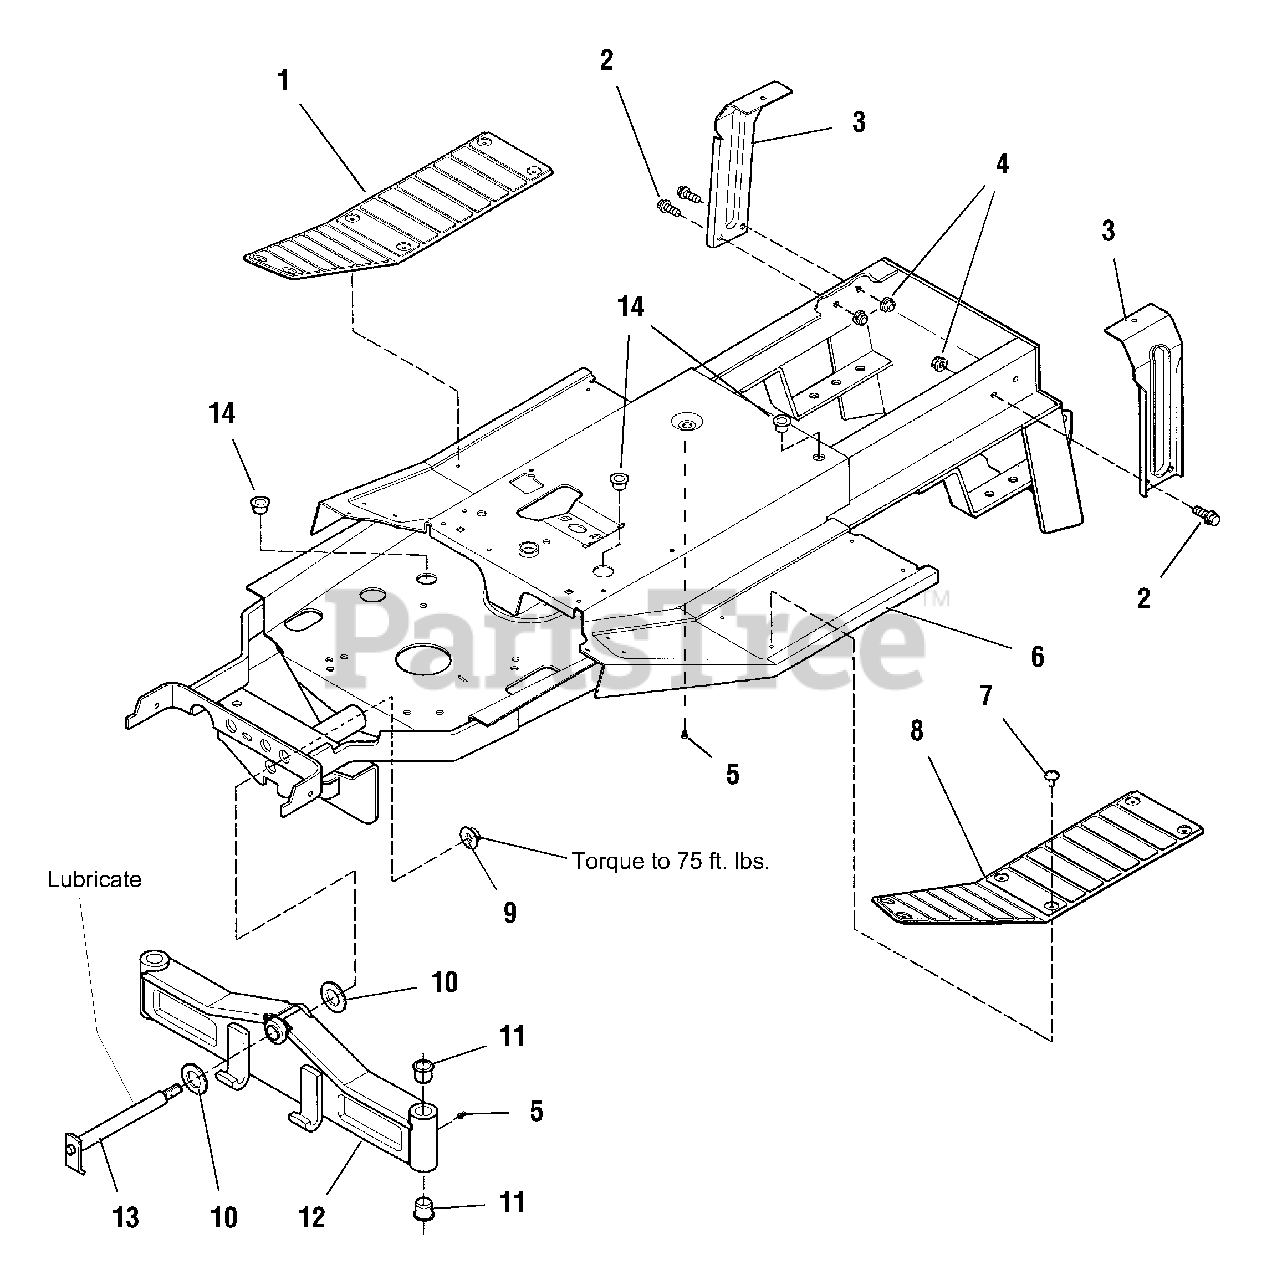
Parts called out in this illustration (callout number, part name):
1	PAD, Footrest, RH
2	CAPSCREW, Hex Whizlock, 3/8-16 x 1
3	SUPPORT, Seat
4	NUT, Hex, Esna Lock, 3/8-16
5	GREASE, Fitting
6	FRAME ASSY.
7	FASTENER, Panel
8	PAD, Footrest, LH
9	NUT, Hex, Full Lock, 3/4-16
10	WASHER, Special
12	AXLE ASSY., Front
13	AXLE PIVOT ASSY.
14	BUSHING, Snap
